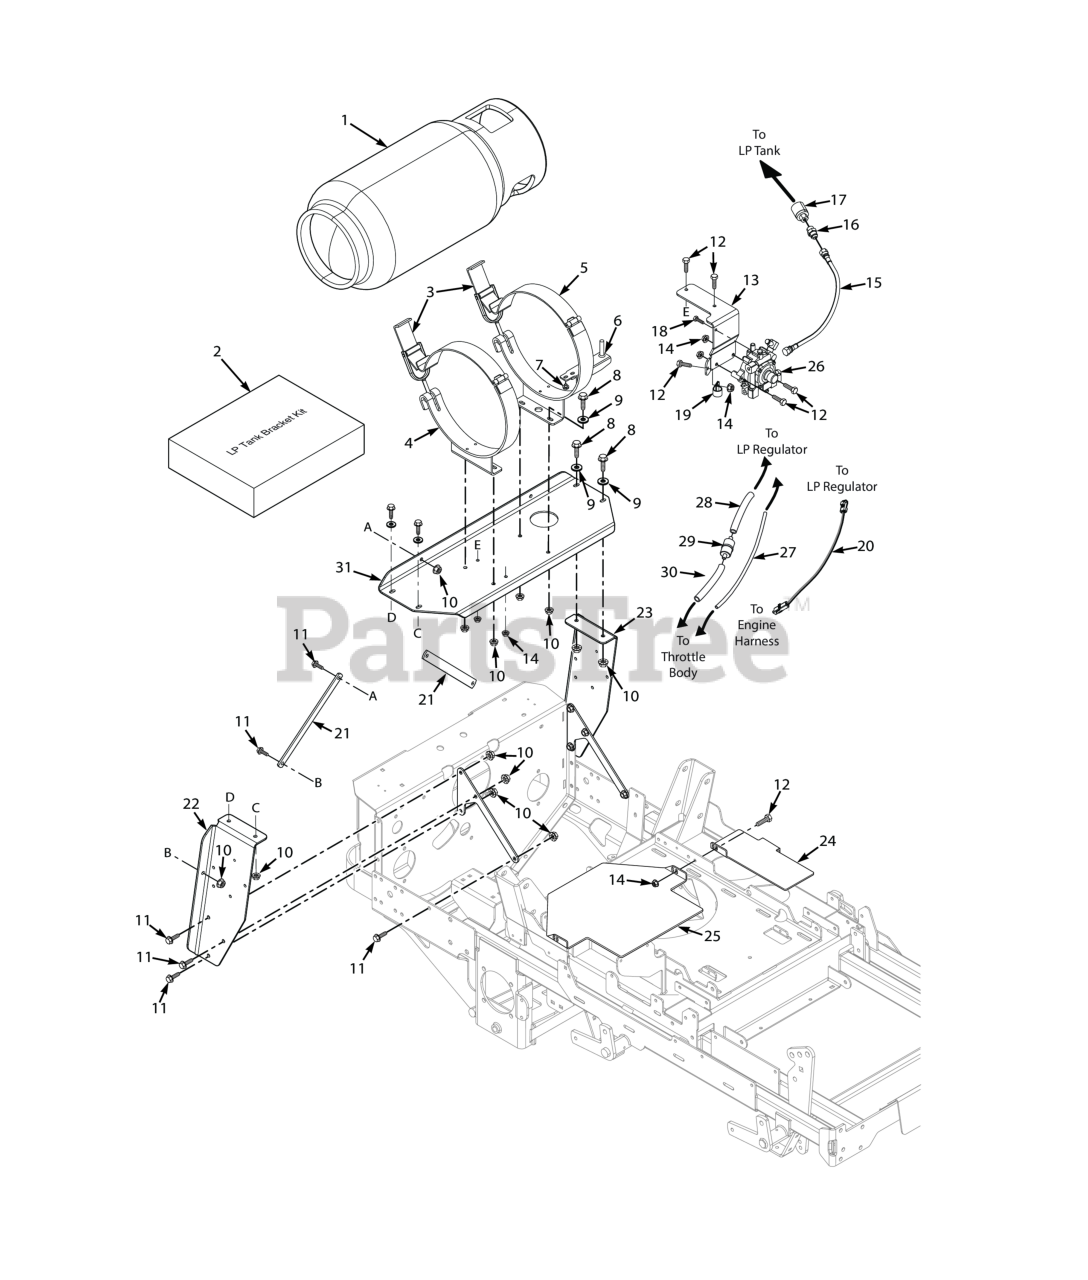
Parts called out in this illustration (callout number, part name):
1	LP Tank - Vapor
2	Mounting Bracket Kit
3	Handle, LP Tank Mounting Bracket
4	Mounting Bracket, LP Tank Rear
5	Mounting Bracket, LP Tank Front
6	LP Tank Locating Bracket
7	Bolt, Hex Head 1/2-13 x 1.5"
8	Bolt, Hex Head, 3/8-16 x 1 Gr. 5
9	Flatwasher, 3/8" Special (.391 x .938 x .105)
10	NUT, 3/8-16 SERRATED FLANGE HEX HEAD
11	Bolt, Hex Head, 3/8-16 x 3/4"
12	BOLT, SERRATED FLANGE HEX HEAD 5/16-18 X 3/4"
13	Mounting Bracket, Regulator
14	Nut, Serrated Flange 5/16-18 (Right Front Engine Mounting, Briggs and Kohler Only)
15	LP Fuel Line, 17"
16	Adapter Fitting, 9/16-18 SAE x 1/4" Pipe
17	LP Quick Coupler
18	BOLT, HEX HEAD, 1/4-20 X 3/4 GR.5
19	Clamp, Cable 3/4" ID.
20	Adapter, Wire Harness
21	Brace, Engine Mounting
22	Mounting Bracket, Tank Support - RH
23	Mounting Bracket, Tank Support - LH
24	Cover, Fuel Fill Hole
25	Cover, Fuel Tank Hole
26	LP Regulator
27	Hose
28	Hose
29	Fuel Filter
30	Hose
31	Support, LP Tank
